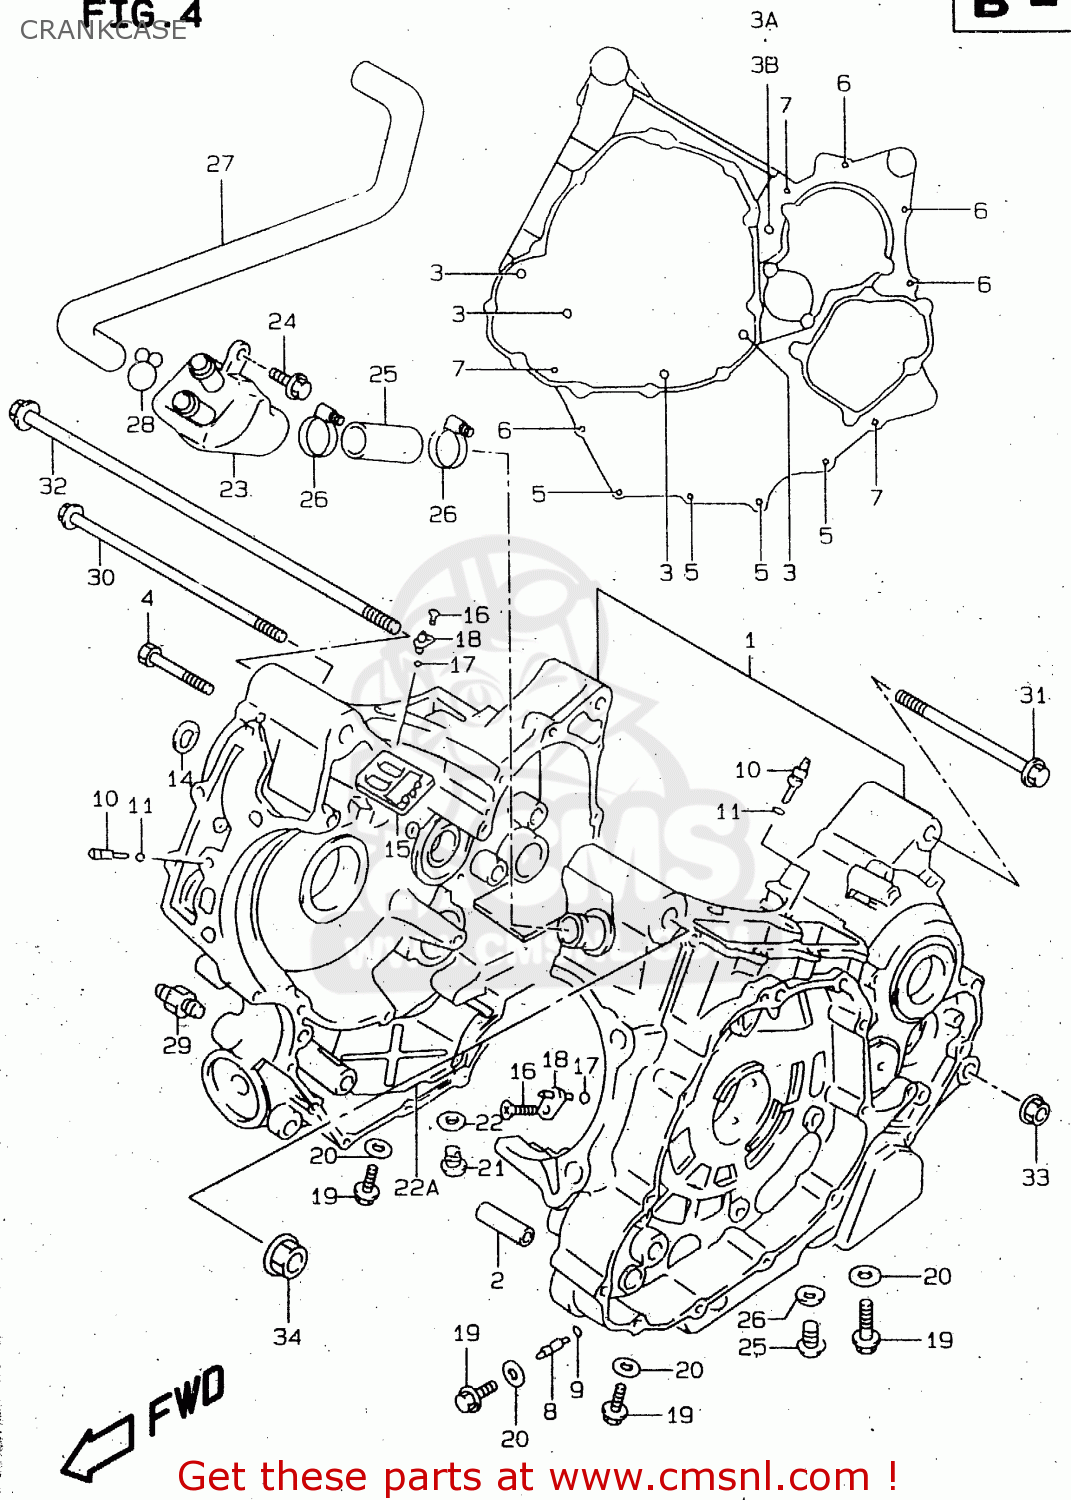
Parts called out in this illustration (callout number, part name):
1	CRANKCASE SET
2	PIN,CRANKCASE
3	BOLT
3A	BOLT(8X125)
3B	WASHER
4	BOLT(8X110)
5	BOLT
6	BOLT
7	BOLT
8	JET,AIR(14)
9	O RING(D:1.2,ID:4)
10	JET,OIL GALLERY
11	O RING(D:1.2,ID:4)
12	PLUG
13	GASKET(13.8X18.8X4.8) (NAS)
14	O RING(D:1.9,ID:12.6)
15	VALVE ASSY,BREATHER
16	SCREW(6X12)
17	O RING(D:1.2,ID:4)
18	JET,PISTON COOLING
19	BOLT
20	GASKET(8.2X14X1).6 (NAS)
21	PLUG
22	GASKET(16X22X2) (NAS)
22A	SEPARATOR,OIL
23	TANK,OIL RETURN
24	BOLT
25	HOSE,OIL RETURN
26	CLAMP
27	HOSE,BREATHER
28	CLIP
29	SWITCH ASSEMBLY,OIL PRESSURE
30	BOLT(10X205)
31	BOLT(10X155)
32	BOLT(12X200)
33	NUT
34	NUT
